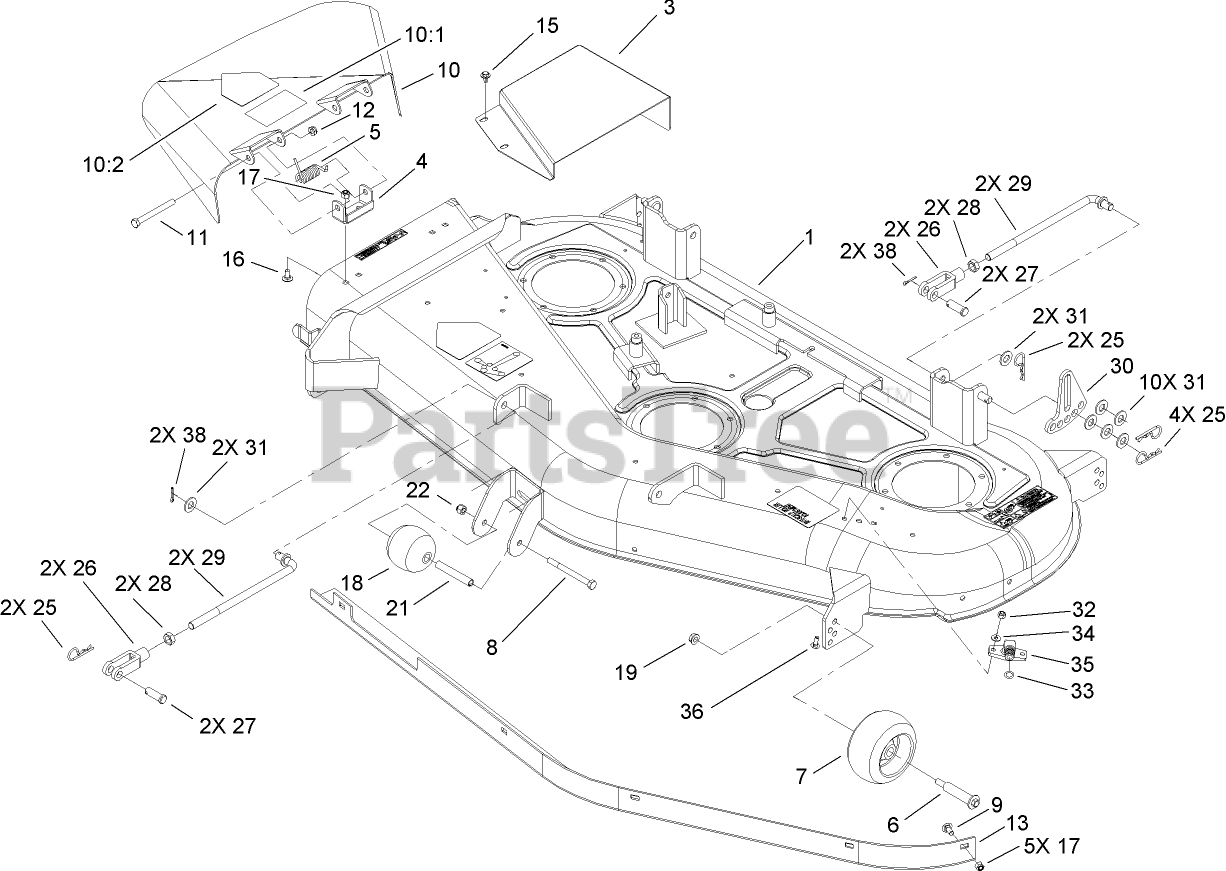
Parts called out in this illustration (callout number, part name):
1	52 INCH DECK ASM
3	COVER-BELT, RH
4	BRACKET-PIVOT
5	SPRING
6	BOLT-SHOULDER
7	ROLLER-SCALP, ANTI
8	SCREW-HH
9	SCREW-CARR
10:1	DECAL-DANGER
10:2	DECAL-DANGER
11	SCREW-HH
12	NUT-HEX
15	SCREW-HHFTF
16	SCREW-CARR
17	NUT-LOCK, NI
18	ROLLER
19	NUT-LOCK, NI
21	TUBE-SPACER, WHEEL
22	NUT-LOCK, NI
25	PIN-COTTER
26	CLEVIS
27	PIN-CLEVIS
28	NUT-JAM
30	LINK-HOC, ADJUSTING
31	WASHER-FLAT
32	NUT-LOCK, NI
33	O-RING
34	WASHER-FLAT
36	BOLT-CARR
38	PIN-COTTER
